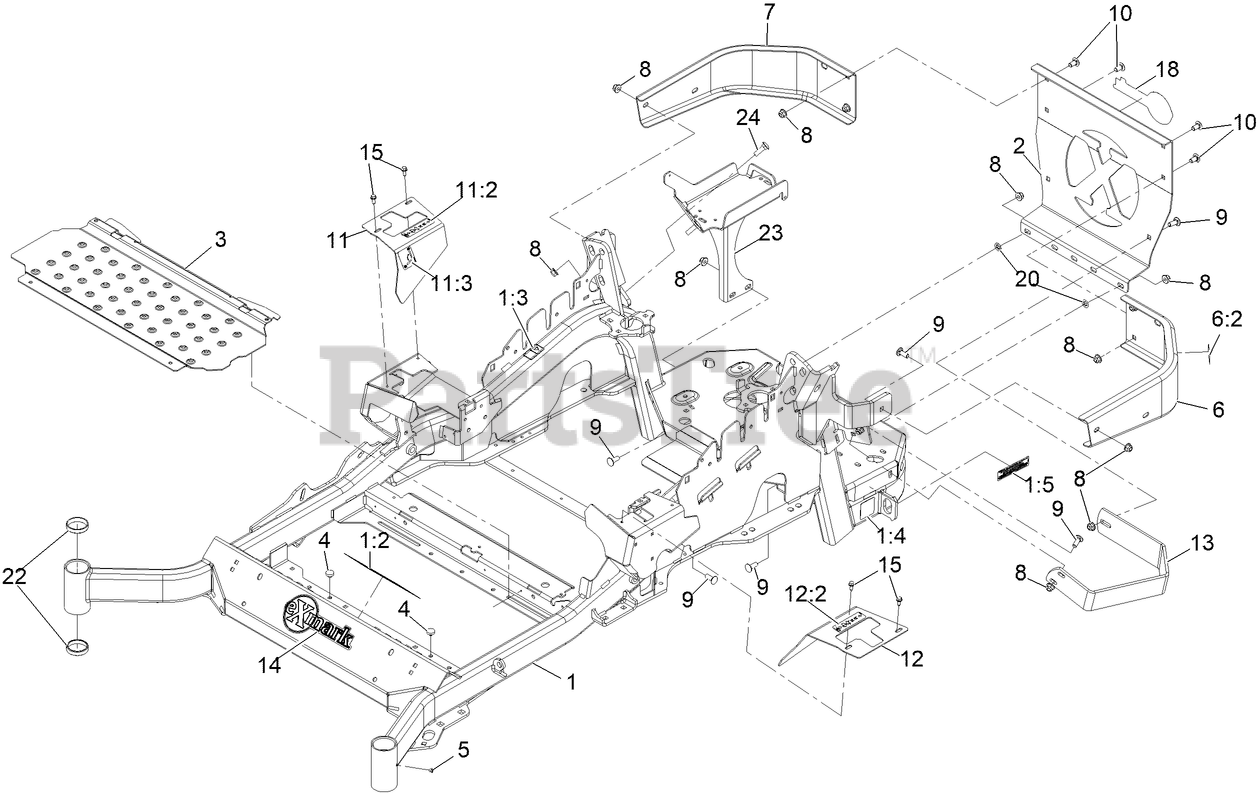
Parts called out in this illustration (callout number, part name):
1	MAINFRAME SERVICE ASM - 60
1:2	DECAL-DANGER
1:3	DECAL-WARNING
1:4	DECAL-HAZARD, PINCHED FINGER
1:5	DECAL-ARRESTOR, SPARK
2	PLATE,REAR GUARD
6	LH BUMPER ASM
6:2	DECAL-WARNING
7	BUMPER-RH
8	NUT-HF, NI
9	SCREW-CARR
10	SCREW-CARR
11	RH MOTION CONTROL COVER ASM
11:2	DECAL-CONTROL, MOTION
11:3	DECAL-PARK BRAKE, CE
12	LH MOTION CONTROL COVER ASM
12:2	DECAL-CONTROL, MOTION
13	GUARD-MUFFLER
14	DECAL-EXMARK
15	SCREW-HWH
18	DECAL, EXMARK LOGO
20	NUT-PUSH
22	CUP-BEARING
23	BATTERY MOUNT ASM
24	BOLT-CARR
